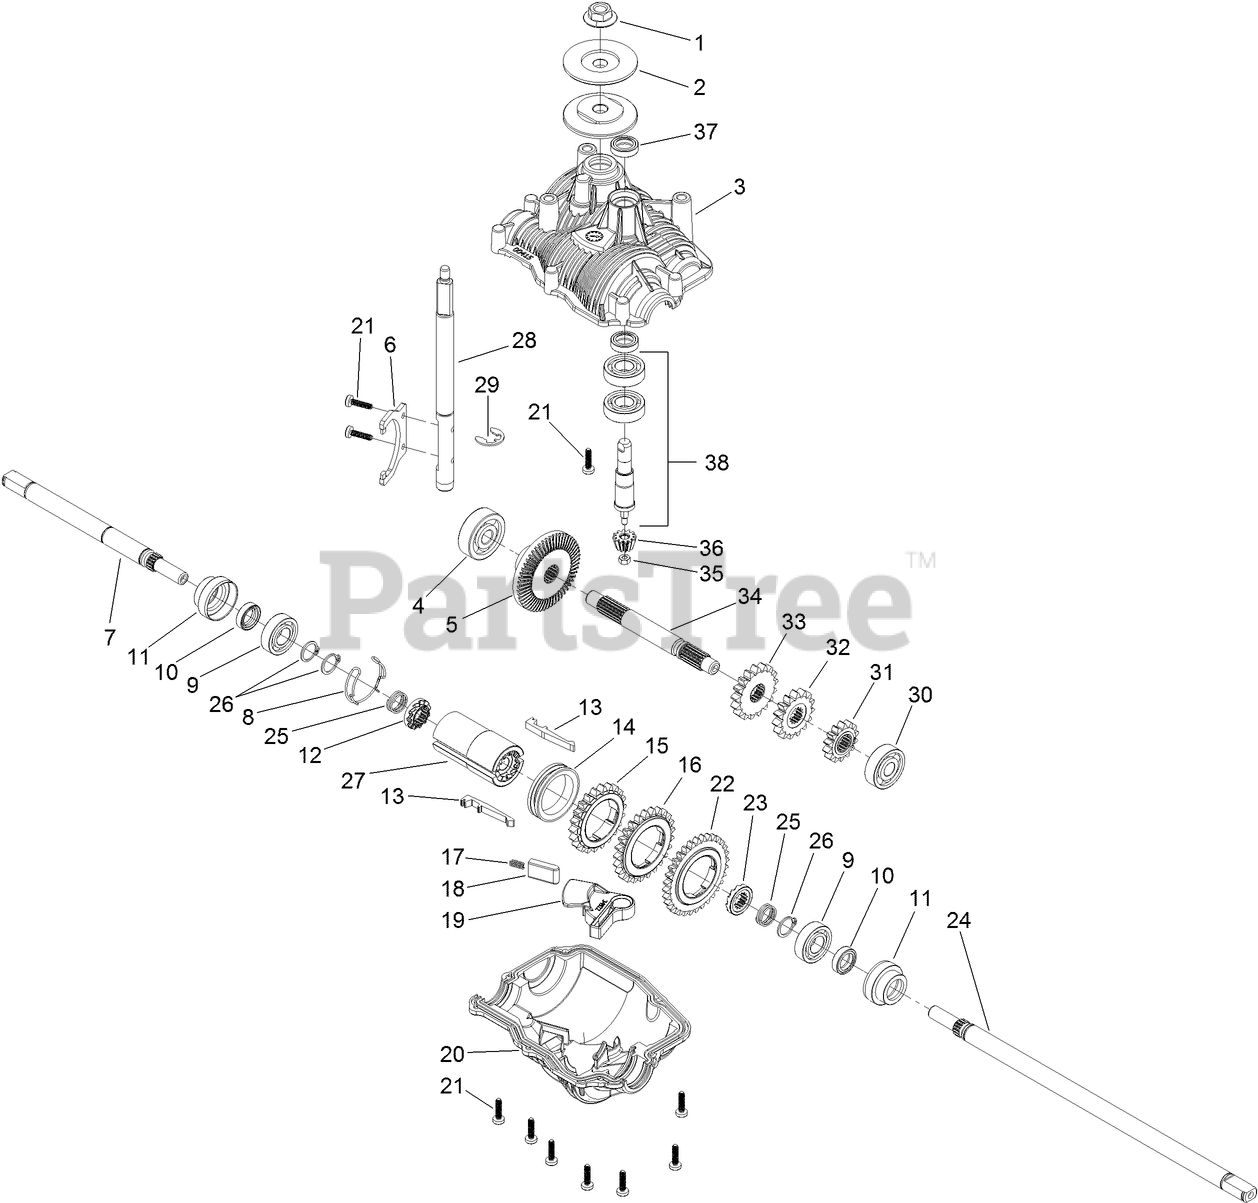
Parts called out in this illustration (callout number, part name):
1	NUT-FLANGE
2	FLANGE-PULLEY
3	CASE-UPPER, TRANSMISSION
4	BEARING-BALL
5	GEAR-BEVEL, 53 TOOTH
6	FORK-SHIFT
7	SHAFT-OUTPUT, SHORT
8	SPRING-RETAINING
9	BEARING-BALL
11	BUSHING-SHAFT, OUTPUT
12	CLUTCH-DOG
13	KEY-SHIFT
14	RING-SHIFT
15	GEAR-OUTPUT, 22 TOOTH
16	GEAR-OUTPUT, 25 TOOTH
17	SPRING-INDEXING, SHIFTER
18	PIN-INDEXING, SHIFTER
19	LEVER-INDEXING, SHIFTER
20	CASE-LOWER, TRANSMISSION
22	GEAR-OUTPUT, 32 TOOTH
23	CLUTCH-DOG, RH
24	SHAFT-OUTPUT, LONG
25	SPRING-COMPRESSION, CLUTCH
26	RING-RETAINING
27	HUB-GEAR, OUTPUT
28	SHAFT-SHIFT
29	RING-RETAINING
30	BEARING-BALL
31	GEAR-INTERMEDIATE, 14 TOOTH
32	GEAR-INTERMEDIATE, 15 TOOTH
33	GEAR-INTERMEDIATE, 17 TOOTH
34	SHAFT-INTERMEDIATE
35	NUT-SHAFT, INPUT
36	GEAR-BEVEL, 12 TOOTH
38	SHAFT-INPUT
